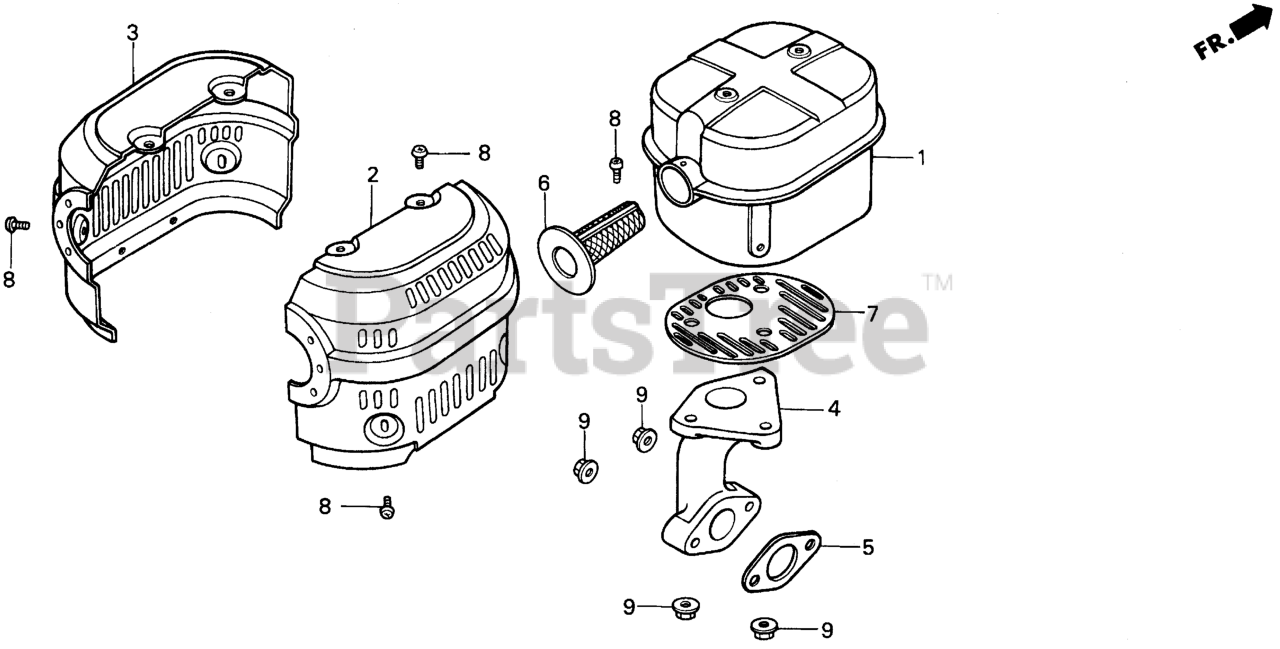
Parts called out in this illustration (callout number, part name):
1	MUFFLER
2	PROTECTOR, R. MUFFLER (ALUMINIZED)
3	PROTECTOR, L. MUFFLER (ALUMINIZED)
4	PIPE, EX.
5	GASKET, EX. PIPE Use up to Engine SN 2949254.
5	GASKET, EX. PIPE (WACKER)
6	ARRESTER, SPARK
7	GASKET, MUFFLER (ARRESTER) (NOT AVAILABLE)
8	SCREW, TAPPING (5X8)
9	NUT, FLANGE (8MM)
